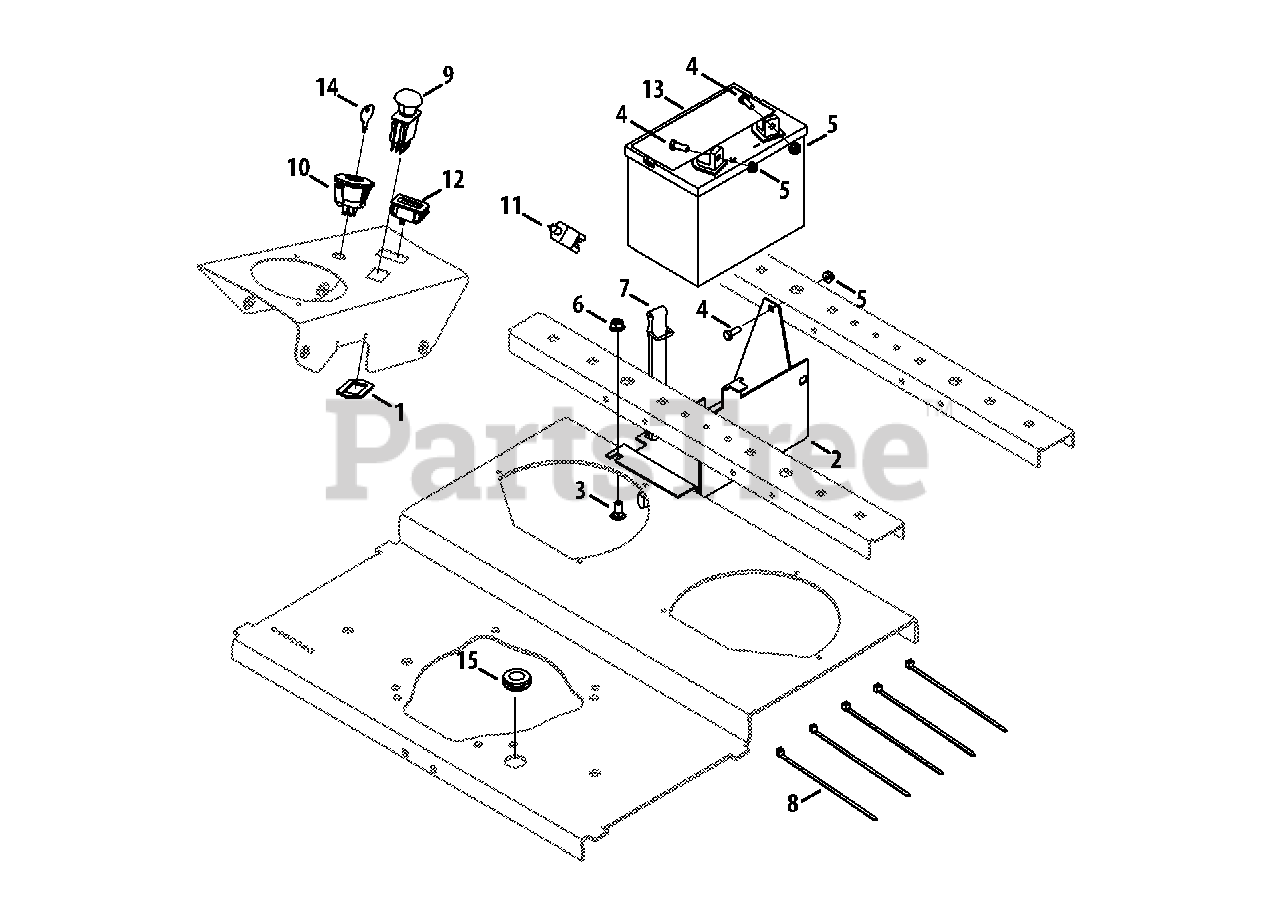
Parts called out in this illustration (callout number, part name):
1	PTO Switch Bracket
2	Battery Bracket
3	Carriage Bolt, 3/8-16 x .750
4	Hex Cap Screw, 1/4-20 x .75
5	Nut, 1/4-20, Flangelock
6	Nut, 3/8-16, Flangelock
7	Battery Strap
8	Cable Tie
9	Electric PTO Switch
10	Key Switch
11	Plunger Switch, NO/NC
12	Hour Meter
14	Key, Assembly
15	Rubber Grommet, .75 x 1.062 x .50
